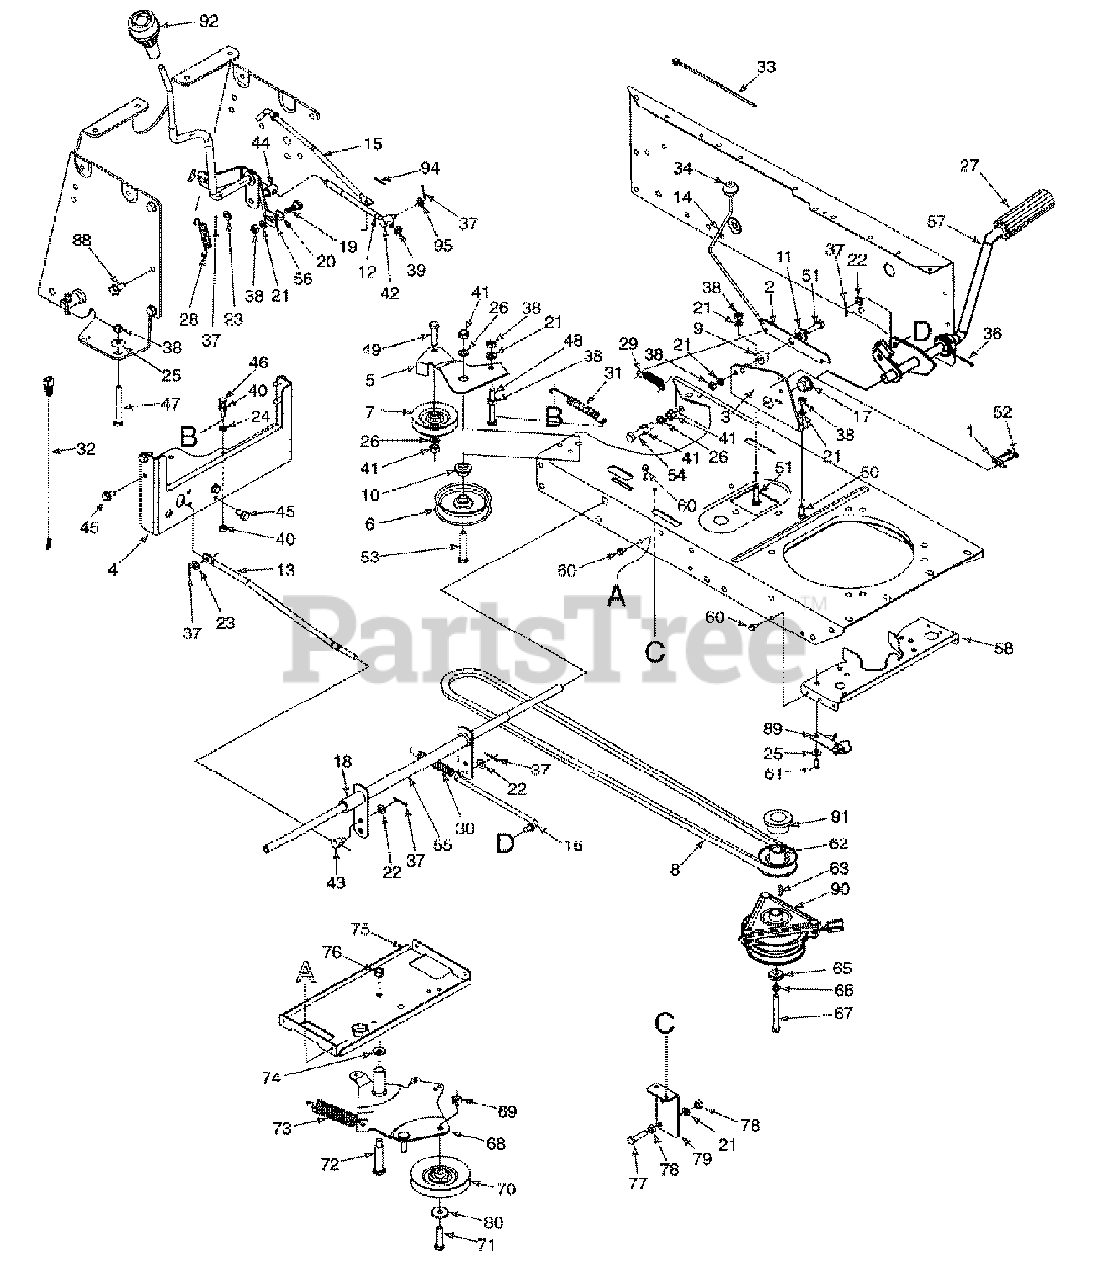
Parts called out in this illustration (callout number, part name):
1	Switch Plate
7	Idler Pulley
8	"V"-Belt
9	Spacer .34" I.D. x .44" Lg.
10	Shld. Spacer .38" I.D.
11	Shld. Spacer
12	Speed Selector Rod
13	Neutral Return Rod
14	Brake Lockout Rod
15	Hydro Disengagement Rod
16	Brake Link Rod
17	Hex Flange Bearing
18	Nyliner Flange Bearing
20	Spr. Wash. 7/16" I.D.
21	L-Wash. 5/16" I.D.
22	Fl-Wash. 5/16" I.D.
23	Fl-Wash. .38" I.D.
24	L-Wash. 1/4" I.D.
25	Bell-Wash. .345" I.D.
26	L-Wash. 3/8" I.D.
27	Foot Pad
28	Ext. Spring 2.75" Lg.
29	Ext. Spring 2.51" Lg.
30	Ext. Spring 4.74" Lg.
31	Ext. Spring 4.97" Lg.
32	Transmission Wire
36	Cotter Pin 1/8" Dia. x 1" Lg.
37	Cotter Pin 3/32" Dia. x 1" Lg.
38	Hex Nut 5/16-18 Thd. (Gr. 5)
39	Hex Jam Nut 5/16 Thd. L.H.
40	Hex Nut 1/4-20 Thd. (Gr. 5)
41	Hex Nut 3/8-16 Thd. (Gr. 5)
42	Ferrule 5/16-24 Thd. L.H.
43	Ferrule 5/16-18 Thd.
44	Ferrule 3/8-24 Thd.
45	Hex Wash. TT-Tap Scr. 5/16 x .75" Lg.
46	Hex Bolt 1/4-20 x 1.25" Lg.
47	Hex Bolt 5/16-18 x 3" Lg.
48	Hex Bolt 5/16-18 x 2.75" Lg.
49	Hex Bolt 3/8-16 x 1.5" Lg.
50	Hex Bolt 5/16-18 x .75" Lg.
51	Hex Bolt 5/16-18 x 1.25" Lg.
52	Hex HD Tapp Scr. #10-16 x .75" Lg.
53	Hex Bolt 3/8-16 x 2.25" Lg.
54	Hex Bolt 3/8-16 x 2" Lg. (Gr. 5)
57	Hydro Foot Pedal Ass'y.
61	Hex Bolt 5/16-18 x .75" Lg.
62	Engine Pulley
63	Sq. Key 1/4 x 1" Lg.
65	Shld. Spacer .445" I.D.
66	L-Wash. 7/16" I.D.
67	Hex Bolt 7/16-20 x 3.75"
68	Idler Brkt. Deck Ass'y.
69	Hex Cent. L-Nut 3/8-24 Thd.
70	Idler Pulley
71	Hex Bolt 3/8-24 x 1.5" Lg.
72	Shld. Bolt .498" Dia. x 2.05"
73	Ext. Spring 4" Lg.
74	Bell-Wash. .38" I.D. x .88" O.D.
76	Hex Cent. L-Nut 3/8-16 Thd.
77	Hex Bolt 5/16-24 x 1.25" Lg.
78	Hex Nut 5/16-24 Thd. (Gr. 5)
79	Parking Brake Mtg. Brkt.
80	Fl-Wash. .40" I.D. x .875" O.D.
88	Hex AB-Tap Scr. 5/16 x .75"
91	Clutch Spacer
94	Hairpin Clip
95	Fl-Wash. .344" I.D. x .75" O.D.
